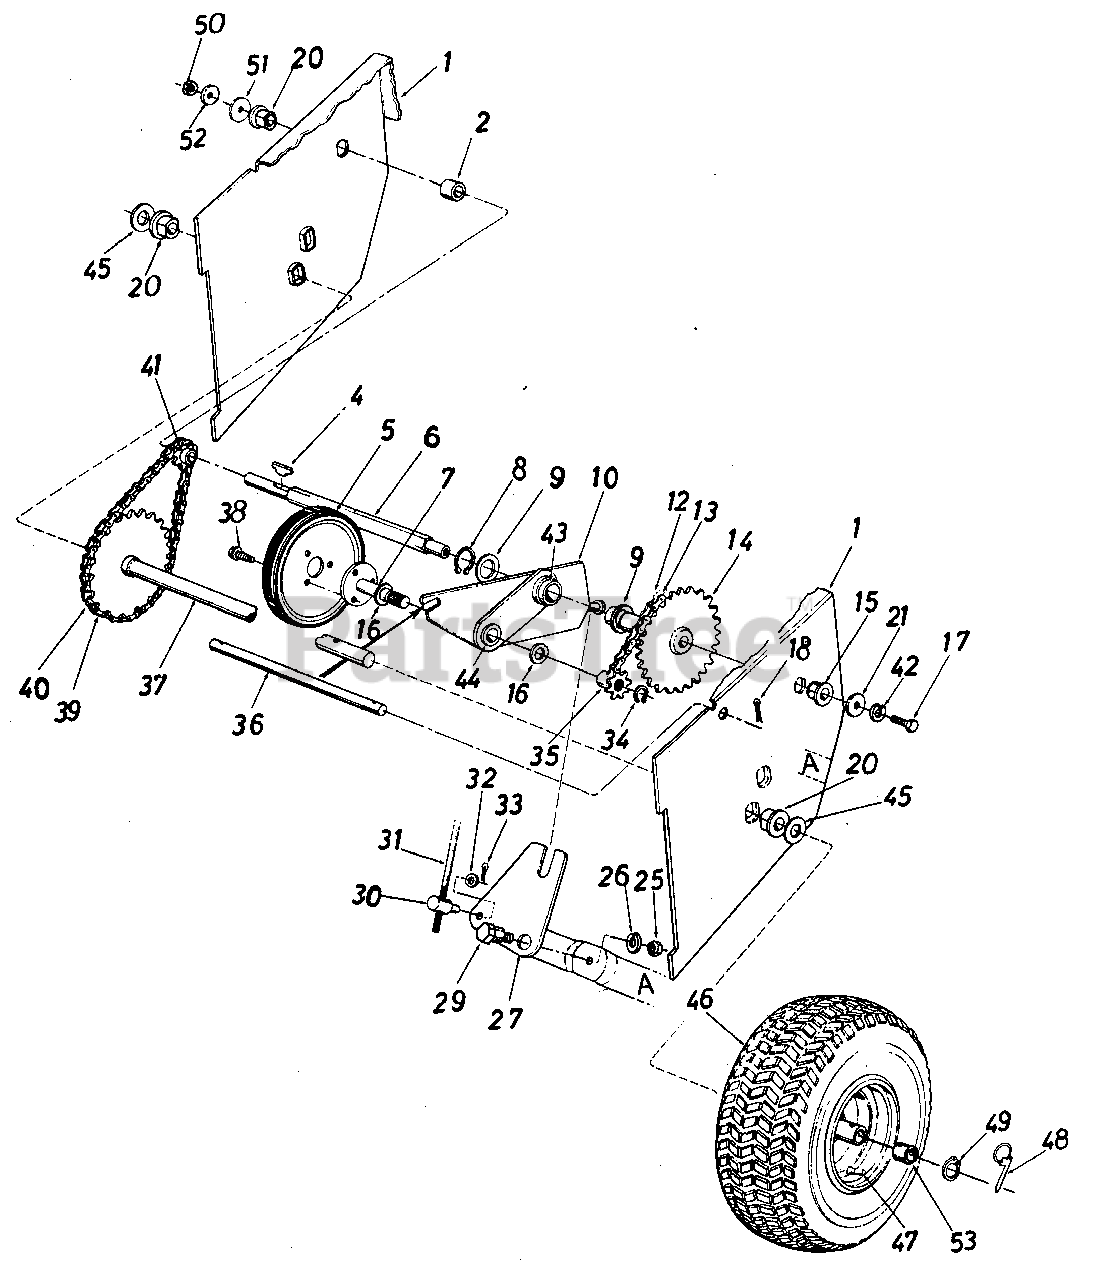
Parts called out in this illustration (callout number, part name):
1	Frame Ass'y.
2	Spacer.50" I.D. x .75" O.D. x .78" Lg .
4	#4 Hi-Pro Key 3/32 x 5/8" Dia.
5	Friction Wheel Ass'y.
6	Hex Shaft
7	Friction Wheel Mounting Plate Ass'y.
8	Snap Ring 1.00" Dia. Shaft
9	Fl-Wash. 1.00" x 1 63" O.D. x .03
10	Sliding Bracket Ass'y.
12	#41 Chain 1/2" Pitch x 35 Links
13	Master Link for #41 Chain
14	32 Teeth Sprocket Ass'y.
15	Hex Flange Brg. .630" I.D.
16	Fl-Wash. .62" I.D. x 1.00" O.D. x .06
17	Hex Lock Bolt 5/16-18 x .62" Lg.
18	Cotter Pin 3/32" Dia. x .75" Lg.
20	Flange Brg. w/ Flats .755" I.D.
21	Fl-Wash. .34" I.D. x 1.12" O.D. x .125
25	Hex Jam Nut 3/8-16 Thd.
26	L-Wash. 3/8" I.D.*
27	Shiftine Linkage Bracket
29	Shld. Bolt .625" Dia. x .170" Lg .
30	Adjustment Ferrule
31	Shifting Rod 5/16" Dia. x 32.50" Lg.
32	Fl-Wash. .34" I.D. x .64" O.D. x .06
33	Cotter Pin 3/32" Dia. x .75" Lg.*
34	Snap Ring .562" Dia. Shaft
35	Sprocket 7 Teeth x .50" Pitch
36	Shaft .50" Dia. x 9.50" Lg.
37	32 Teeth Wheel Axle Ass'y.
38	Hex Wash. Hd. Self-Tap Scr. 5/16-24 x .50" Lg.
39	#420 Chain 1/2" Pitch x 39 Links
40	Master Link for #420 Chain
41	8 Teeth Center Sprocket
42	L-Wash. 5/16" I.D.
43	Bearing
44	Bronze Bearing
45	Fl-Wash. .76" I.D. x 1.49 O.D.
46	Wheel Ass'y. Comp. 13 x 5.0 (550)
47	Air Valve
48	Klick Pin
49	Snap Ring .75 Dia.
50	Hex Ins. L-Nut 1/2-20 Thd.
51	Fl-Wash. .53 I.D. x 1.25 O.D. x .10
52	Bell-Wash. .50 I.D. x 1.0 O.D. x .075
53	Sleeve Brg.
